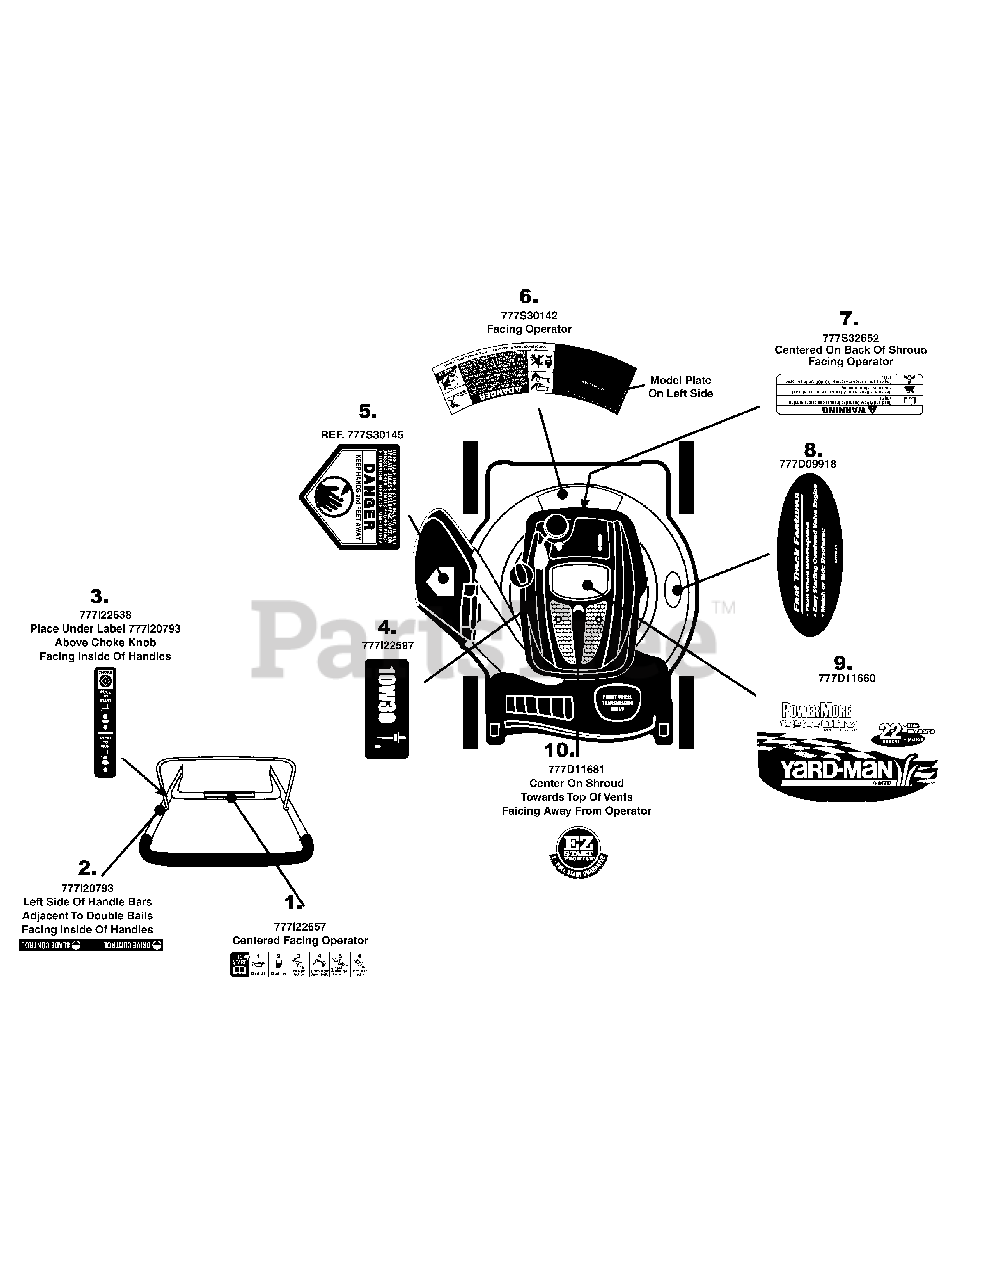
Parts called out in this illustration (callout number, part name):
1	LABEL-MOWER HANDLE
2	LABEL-HANDLE
3	LABEL-MOWER HANDLE:CHOKE START/RUN
4	LABEL:MOWER SHROUD
5	LABEL
6	LABEL-DANGER CURVE
7	LABEL:MOWER:ENGINE SHROUD
8	LABEL-MOWER DECK:YARDMAN
9	LABEL-MOWER SHROUD YARD MAN 22"
10	LABEL-MOWER SHROUD EZ START
